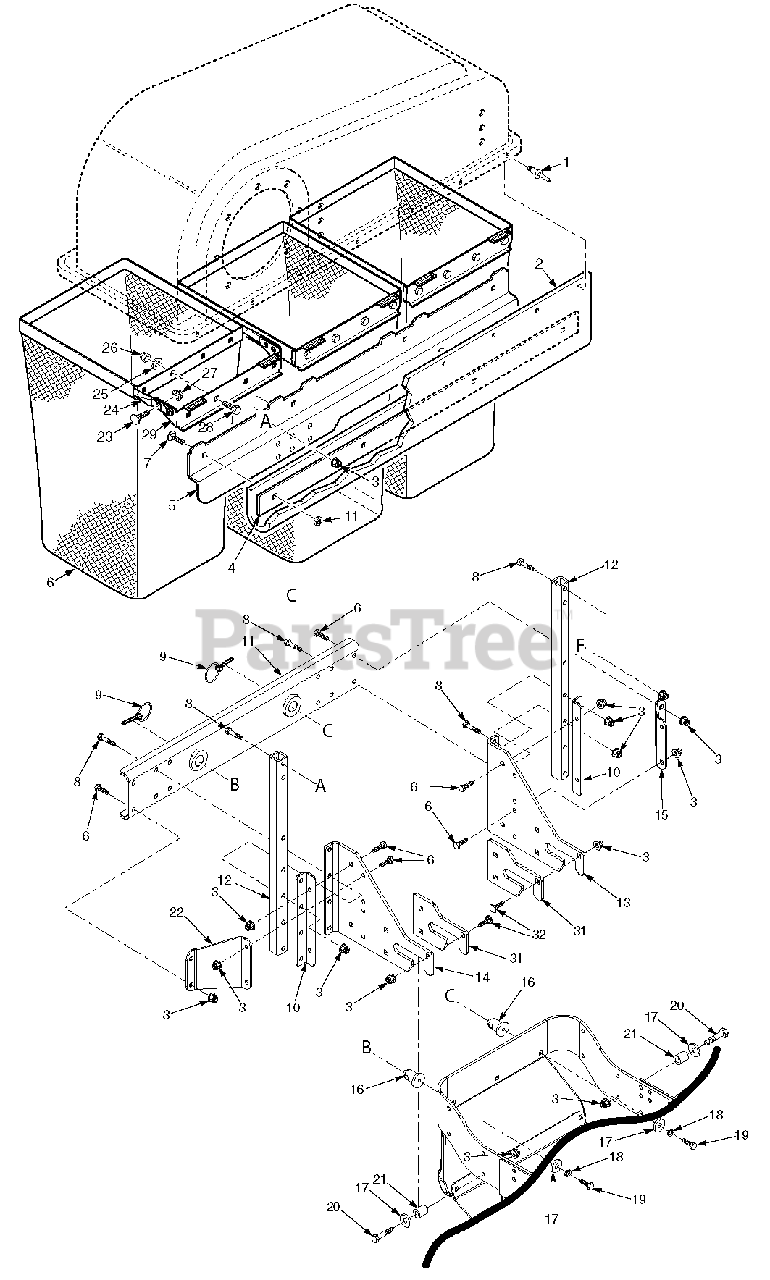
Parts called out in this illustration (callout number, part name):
1	Pop Rivet, 3/16 x .652
2	Seal, Hood
3	Nut, Elastic Flange 3/8-16
4	Retainer, Seal
5	Support, Bag Frame
6	Bag Assembly
7	Bolt, Carriage 1/4-20 x 3/4"
8	Bolt, Hex Head 3/8-16 x 2-1/4"
9	Quick Pin
10	Mounting Bracket, Tube
11	Mounting Bracket Weldment
12	Tube, Upright
13	Mounting Bracket, GC R.H.
14	Mounting Bracket, GC L.H.
15	Angle Bracket, GC
16	Pin, GC Locator
17	Flatwasher, 3/8-.406 x 1.50 x 7 Ga.
18	Lockwasher, 3/8"
19	Bolt, Hex Head 3/8-16 x 1-1/4"
20	Bolt, Hex Head 3/8-16 x 2-1/4"
21	Spacer
22	Angle Bracket, GC
23	Bolt, Carriage 5/16-18 x 3/4"
24	Tube, Bag Support
25	Flatwasher, 5/16-.375 x .875 x .083
26	Nut, Elastic Stop 5/16-18
27	Nut, Serrated Flange 5/16-18
28	Bolt, Hex Head 5/16-18 x 3/4"
29	Mount, Bag Frame Tube
30	Lock Nut, 1/4-20 Center Lock
31	Wear Plate, GC
32	Bolt, Carriage 3/8-16 x 1-1/4"
